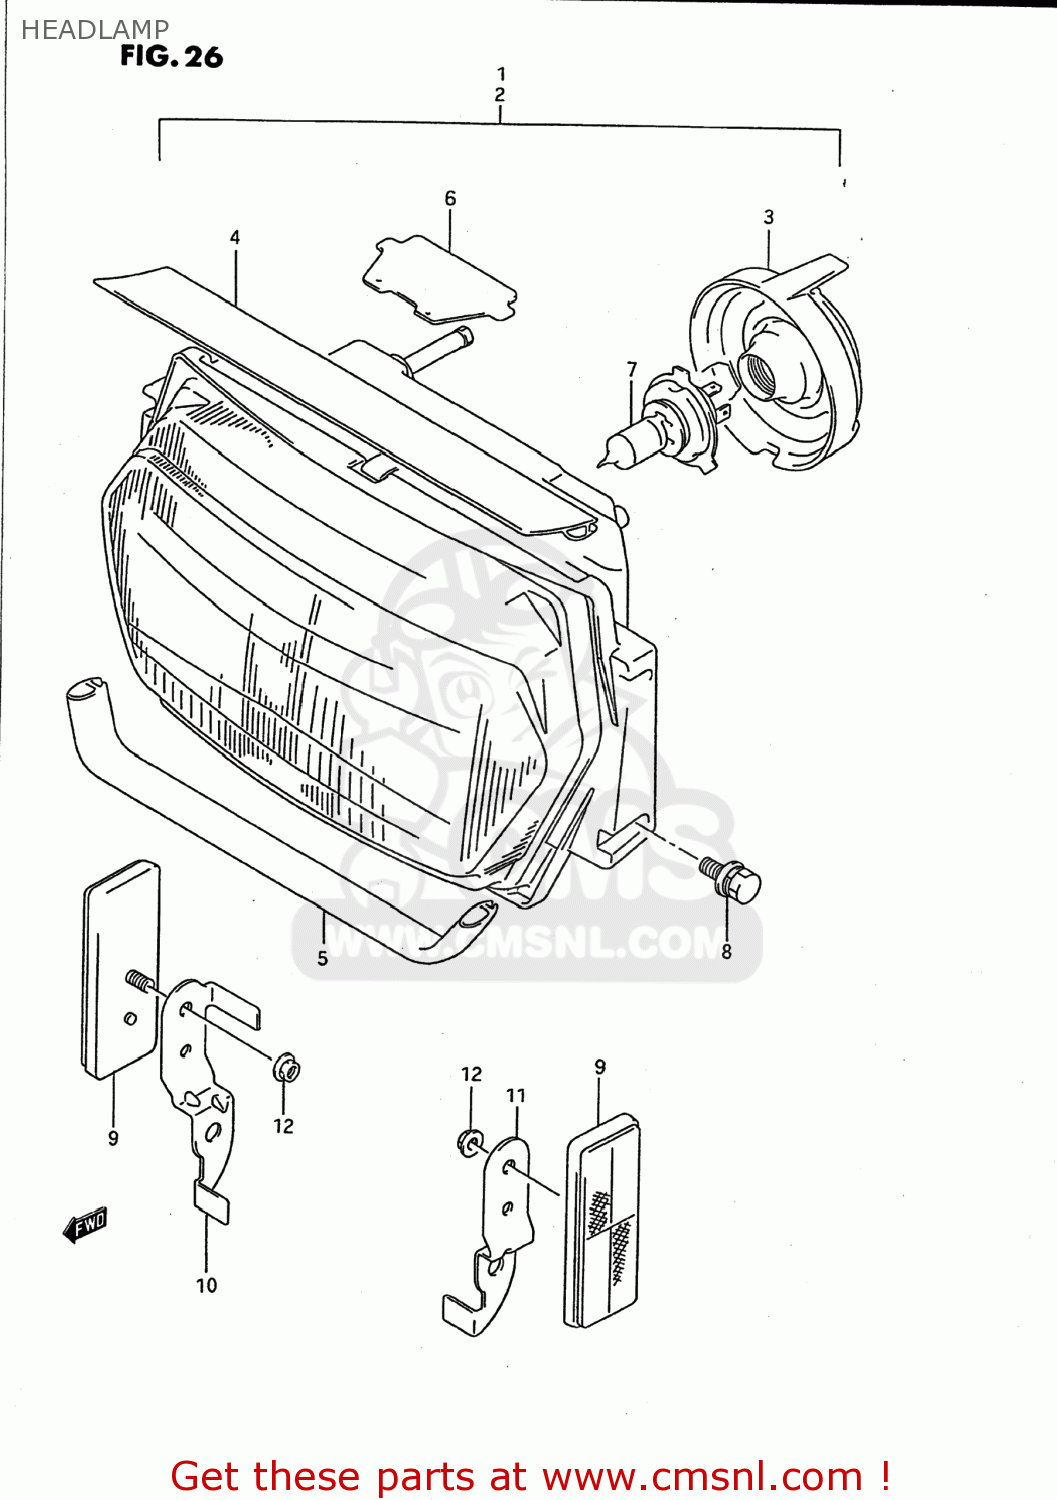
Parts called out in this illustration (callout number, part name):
1	HEADLAMP ASSEMBLY
2	HEADLAMP ASSY
3	COVER,SOCKET
4	GASKET,HEADLAMP (NAS)
5	GASKET,HEADLAMP (NAS)
6	GASKET (NAS)
7	BULB(12V60/55W,H4)
8	BOLT
9	REFLEX REFLECTOR,FR SIDE
10	BRACKET,FR SIDE RR,R
11	BRACKET,FR SIDE RR,L
12	NUT
